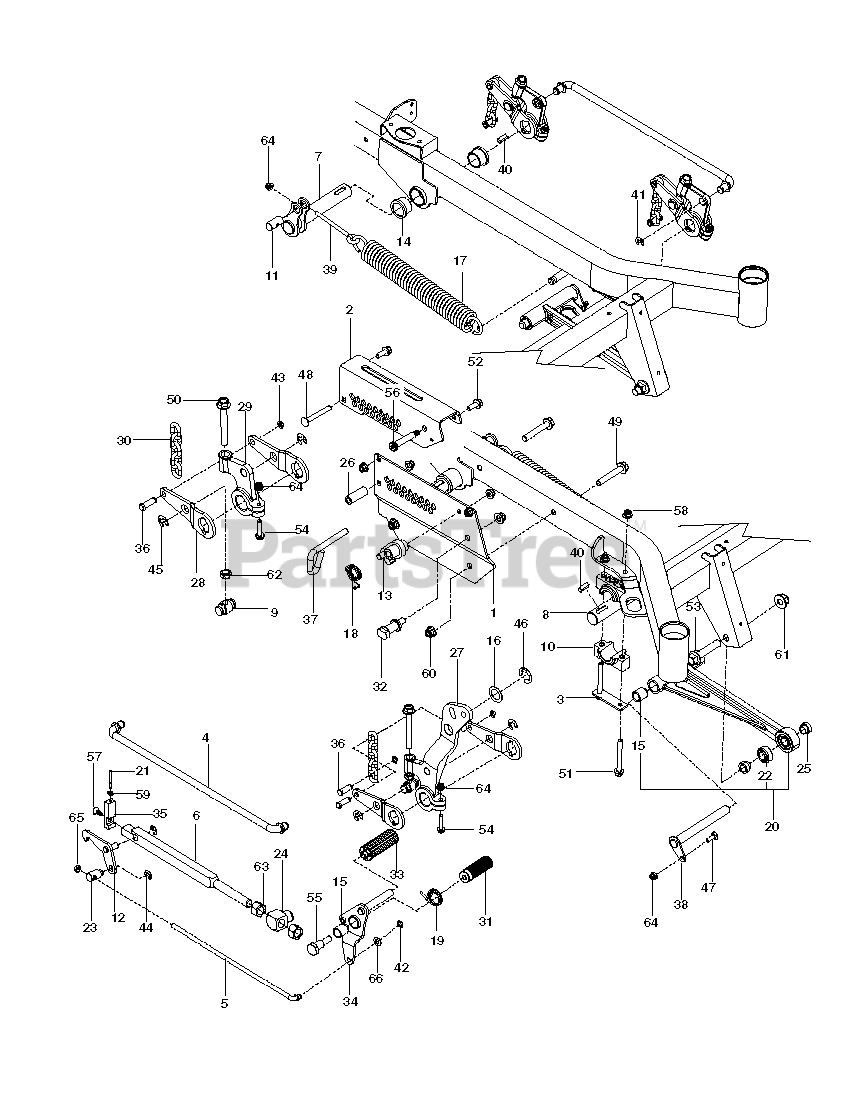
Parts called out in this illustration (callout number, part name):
1	PLATE, INNER HEIGHT, ORANGE
2	PLATE, OUTER HEIGHT ORG
3	PLATE, PILLOW BLACK
5	ROD, HEIGHT LATCH
6	BAR, HEIGHT
7	SHAFT, RR LIFT
8	SHAFT, LIFT, FT
9	SHAFT, LIFT TRUNION WSL
10	BLOCK, PILLOW
11	PIVOT, SPRING
12	LATCH, HEIGHT WLDMT
13	LATCH, TRANSPORT WLDMT
14	BUSHING, FLANGE 1.25 X 1.0
15	BUSHING, SLEEVE 3/4 X 1.0
16	MACHINE BUSHING
17	SPRING, EXTENSION
18	SPRING, TORSION
19	SPRING, TORSION
20	ASSEMBLY, STRUT
21	LINK, INDICATOR
22	BALL JOINT, 3/4" SWIVEL
23	SWIVEL, HEIGHT LATCH
24	SWIVEL, HEIGHT BAR
25	SPACER, STRUT
26	SPACER, HEIGHT PLATE
27	ARM, LIFT LEVER
28	ARM LIFT BLK
29	ARM, CAST LIFT
30	LIFT CHAIN
31	PAD, FOOT PEDAL
32	GUIDE, HEIGHT BAR
33	PEDAL, DECK HEIGHT
34	PEDAL, RELEASE WLDMT
35	CAP, HEIGHT BAR
36	PIN, 7/16 CLEVIS
37	PIN, HEIGHT
38	PIN, STRUT
39	EYE BOLT 4.5`
40	KEY, 5/16 SQ X 1.0
41	E-RING 5/8
42	E RING 3/8"
43	RING, E, 7/16
44	E-RING 1/2 (2 2)
45	E RING 3/4
46	E-RING 1"
47	RHSNB 5/16C X 1
48	3/8-16 X 3` CARR BOLT
49	HFFS 1/2-13 X 3 GD 5 ZD
50	HHFS 1/2-13 X 4 GR 5
51	HHFS 3/8-16 X 3.5 GD 5 ZD
52	HHFS 3/8-16 X 1 GRD 5 ZD
53	HHFS 5/8-11 X 3.0 GD 8 ZD
54	HHFS 5/16-18 X 1.5 GD 5
55	BOLT, SHOULDER
56	BOLT, SHOULDER, 1/2 X 2.25
57	SCREW, 5/16-18 X 3/4 FLAT HEX
58	NUT 3/8-16 HEX FLG NYLOC ZD
59	NUT 1/4-20 JAM
60	NUT, 1/2-13 HEX FLG NYLOC ZD
61	NUT 5/8-11 FLG NYLOC ZD
62	NUT 1/2 HEX JAM
63	NUT 3/4-10 HEX ZD
64	5/16-18 NYLOC FLANGE NUT
65	NUT 3/8-24 JAM
66	WASHER 3/8 SAE FLAT
